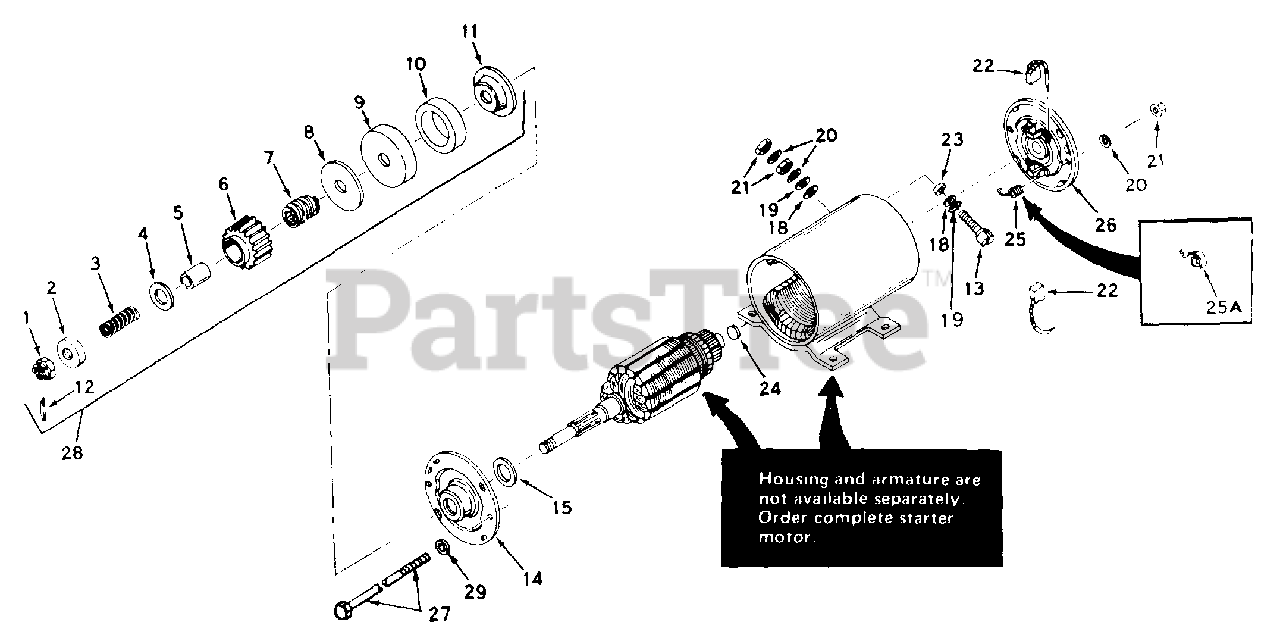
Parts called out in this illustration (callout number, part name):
1	"Nut, Hex
2	Stop, Pinion
3	Spring, Anti-drift
4	Washer, Pinion
5	Sleeve, Anti-drift
6	Gear, Pinion
7	Shaft, Screw
8	Washer, Thrust
9	Cup, Cushion
10	Cushion, Rubber
11	Washer, Thrust
13	Bolt, Terminal
14	Cap Assy, Drive end
15	Washer, Spacing (024 thick)
15	Washer, Spacing (008 thick)
18	Washer, Insulating
19	8Washer, Plain
20	1Washer, Lock
21	3Nut, He
22	Brush & Spring Kit
23	Bushing, Insulating
24	Washer, Spacing
25A	Spring, Brush
26	End Cap Assy, Commutator
27	Bolt, Thru
28	ADrive Assy, Complete
